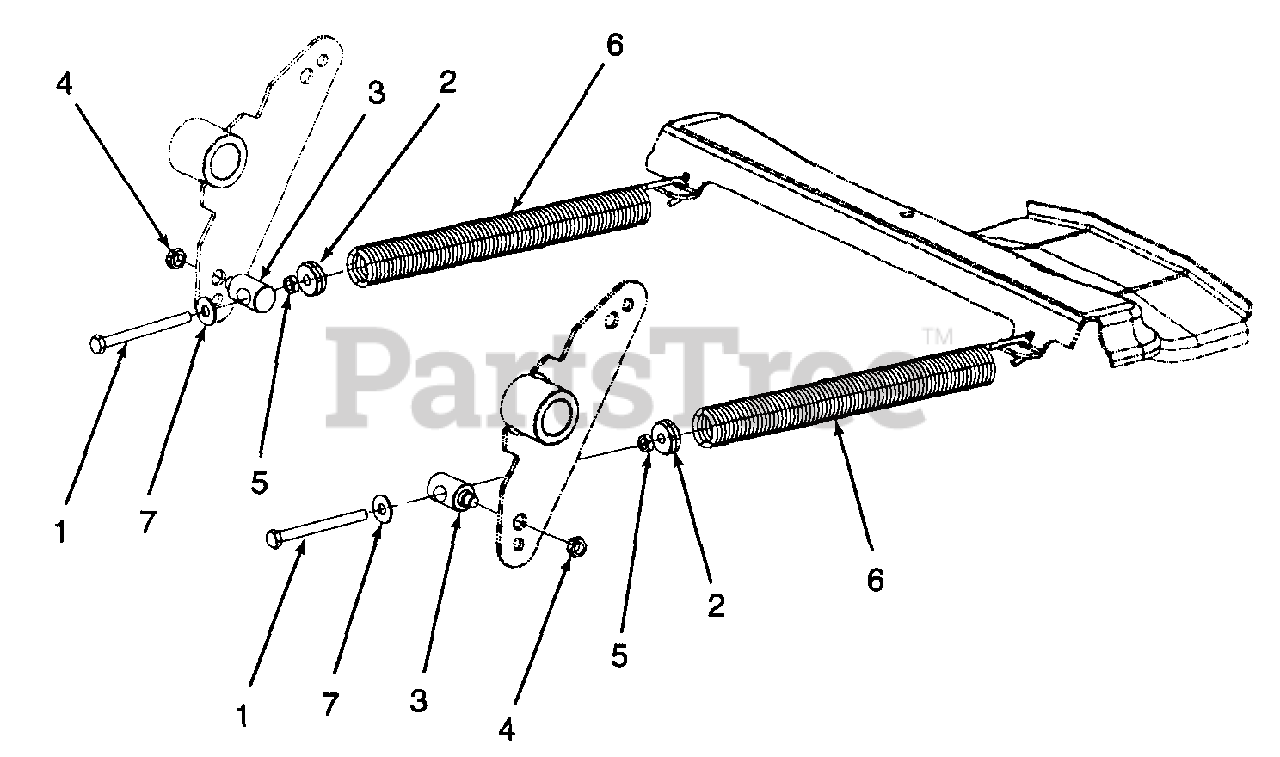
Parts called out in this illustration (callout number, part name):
1	Screw, Hex Cap, Special 5/16-18 x 3.5 GR5
2	Insert, Spring, 5/16-18 Thrd
3	Ferrule, .88 O.D. w/.160 Dia. Shldr
4	Nut, Hex Center Lock Jam, 3/8-24
5	Nut, Hex Jam, 5/16-18 GR5
6	Spring, Extension, 1.25 O.D. x 11.5
7	Washer, Flat, .349 x .879 x .063
